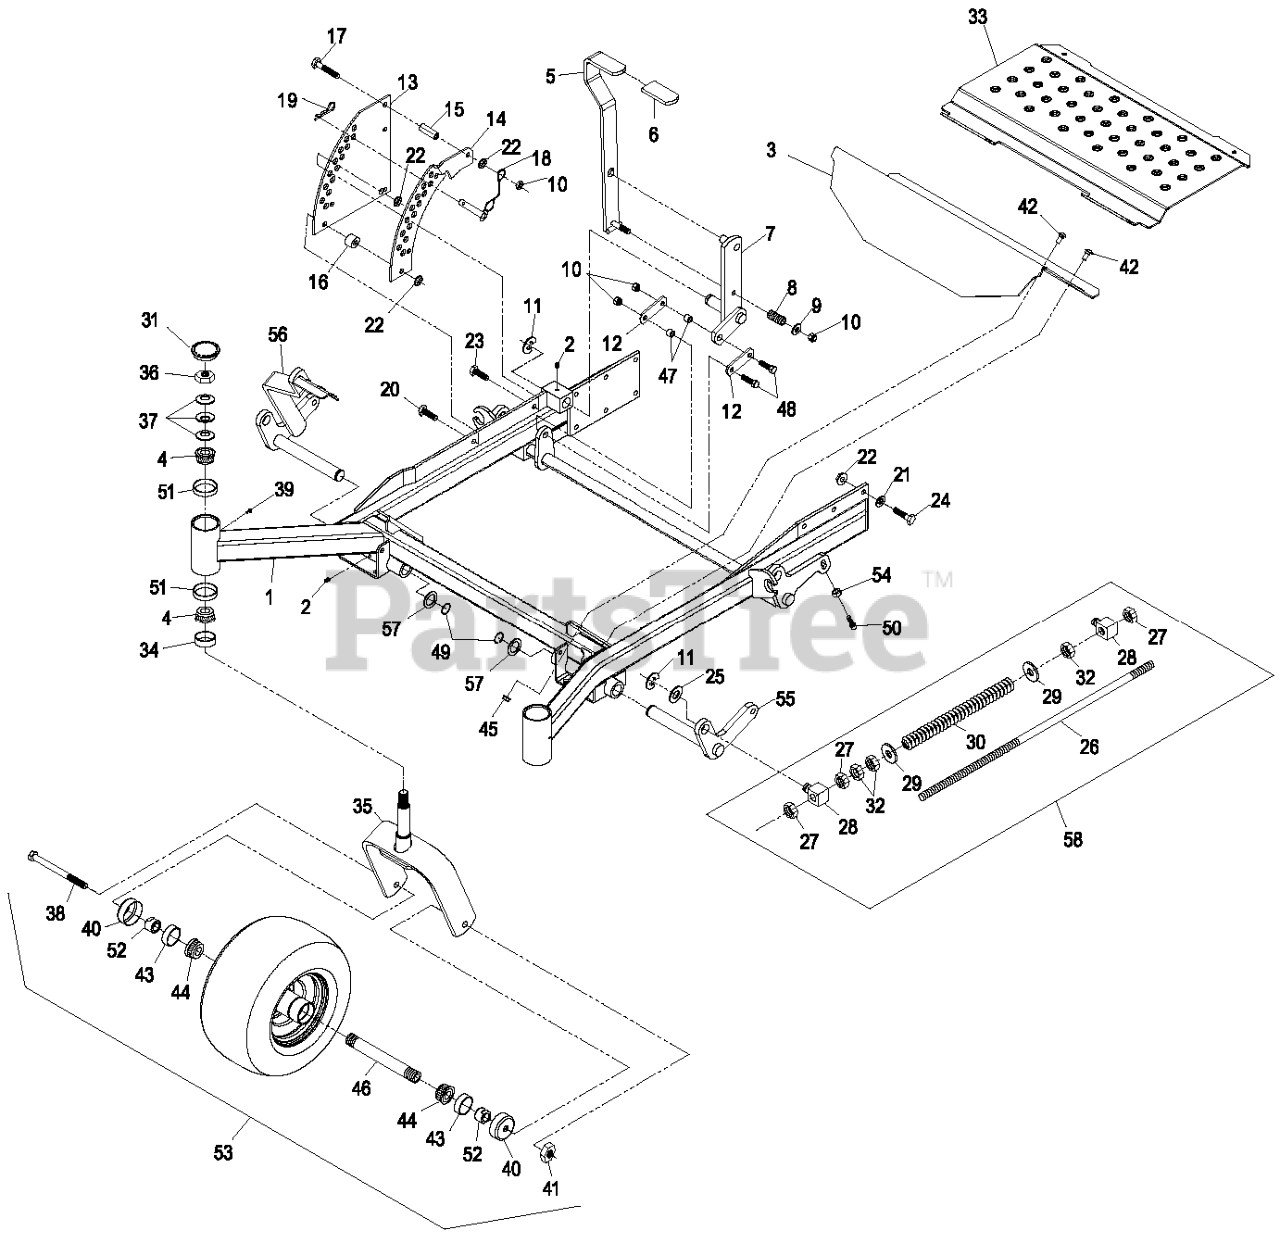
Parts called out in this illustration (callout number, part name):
1	ASM, FRONT FRAME 60"
2	FITTING-GREASE
3	ASM, FLOORPAN FRONT W/DEC
4	Cone-Bearing Tapered Roller
5	LIFT LEVER/GRIP ASM
6	GRIP-LEVER, LIFT
8	SPRING-COMPRESSION
9	WASHER-FLAT
10	NUT-LOCK, NI
11	RING-RETAINING, EXT
12	ARM-LIFT, DECK
13	PLATE-LIFT, DECK
14	PLATE-LIFT,DECK W/DECAL L
15	BUSHING-LEVER, LIFT
16	Stop, Deck Height
17	SCREW-HH
18	PIN-HITCH (W/LANYARD)
19	PIN-COTTER
20	SCREW-HH
21	WASHER-BELLEVILLE
22	NUT-HHF, WHIZ
23	SCREW-HH
24	SCREW-HH
25	WASHER-FLAT
26	ROD-LIFT, DECK
27	NUT-HEX
28	SWIVEL-DECK MOUNT, REAR
29	WASHER-FLAT
30	SPRING,DECK SUPPORT
31	CAP-GREASE
32	NUT-JAM
33	ASM, FLOORPAN LIFTOUT W/D
34	SEAL-GREASE
36	NUT-LOCK, NI
37	WASHER-BELLVILLE
38	SCREW-HH
40	GUARD-SEAL
41	NUT-LOCK, NI
42	BOLT-CARR
43	SEAL-CASTER
44	BEARING-CONE, TAPERED ROLLER
47	BUSHING
48	SCREW-HH
49	RING-RETAINING
50	SCREW-HSH
51	CUP-BEARING
52	SPACER-NUT
54	NUT-JAM
55	WLD,FRONT LIFT SHAFT-LH
56	WLD,FRONT LIFT W/LEVER
57	WASHER-SPACER
58	ASM,FRONT FRAME SPRING
